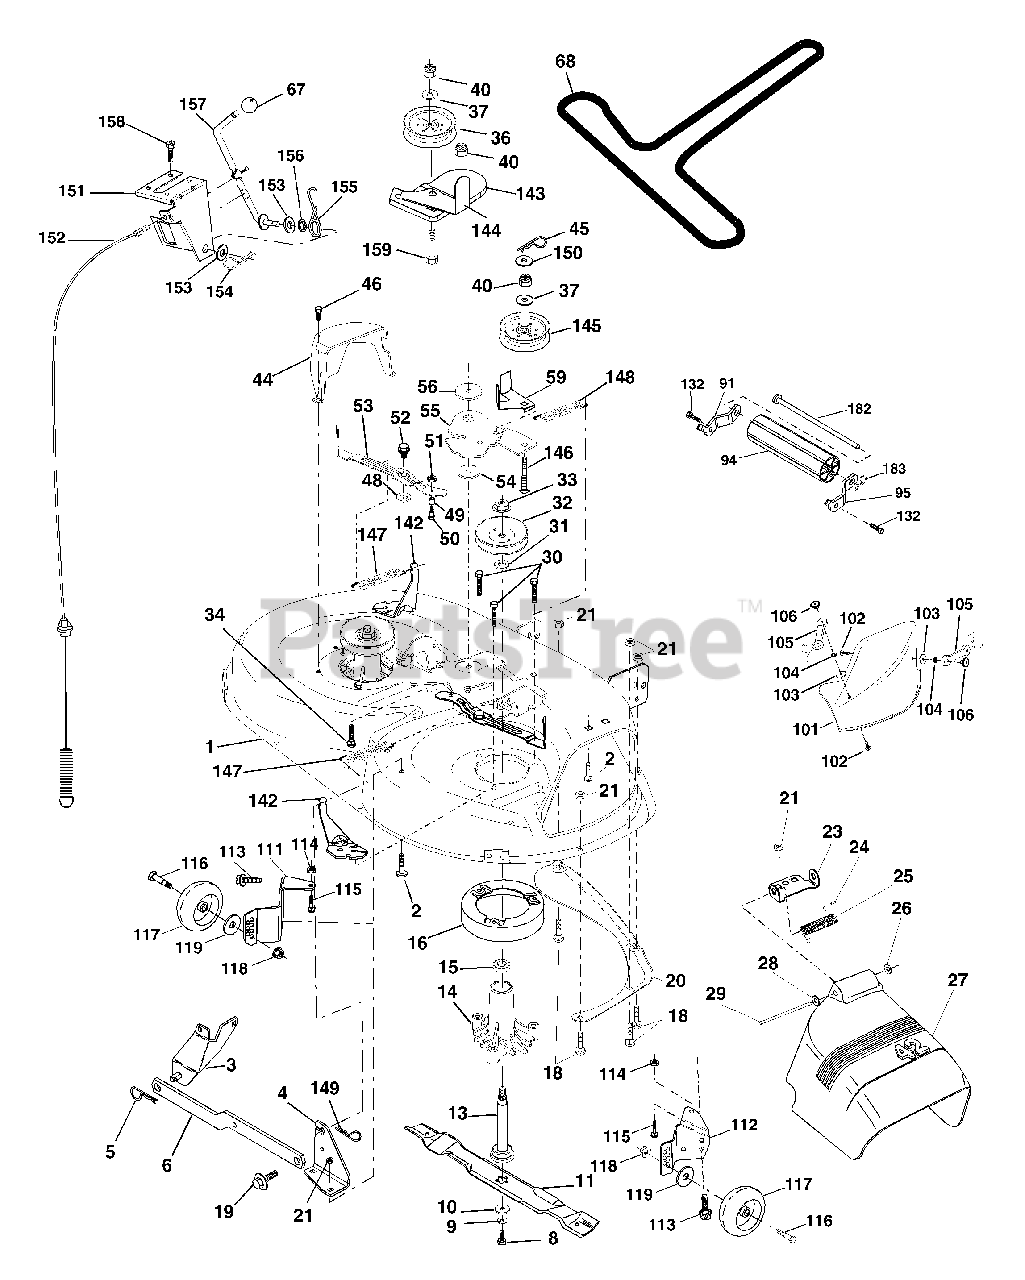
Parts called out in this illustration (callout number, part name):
1	Mower Deck Assembly, 42"
2	Bolt
3	Bracket Asm Fr. Sway Bar 3/42
4	Bracket Asm Deck 42" Sway Bar
5	Retainer Spring
6	Bar Sway Deck
8	Bolt 3/8-24 x 25 Gr. 8 patched
9	Washer, Lock
10	Washer, Hardened
11	Blade, Mulching 42" Std
11	Blade Mower 42" Hi-Lift Std
13	Shaft Assembly, Mandrel, Vented
14	Housing, Mandrel, Vented
15	Bearing, Ball, Mandrel
16	Stripper, Mower Deck
18	Bolt, Carriage 5/16-18 x 5/8
19	Bolt, Shoulder
20	Baffle, Vortex
21	Nut
23	Bracket, Deflector Mower 42"
24	Cap, Sleeve 80 x 112 Blk Mower
25	Spring, Torsion, Deflector 2 52
26	Nut, Push Phos & Oil
27	Shield, Deflector 42" Blk
28	Washer 11/32 x 5/8 x 16 Ga.
29	Rod, Hinge 42" 6 75 W/G
30	Screw Thdrol
31	Washer, Spacer Mower Vented
32	Pulley, Mandrel
33	Nut, Toplock 9/16
34	Bolt
36	Pulley, Idler, Flat
37	Washer 13/32 x 13/16 x 16 Ga.
40	Nut
44	Guard, Mandrel, LH
45	Retainer
46	Screw, Thdrol 1/4-20 x 5/8 T
48	Washer, Hardened
49	Roller Assembly, Cam Follower
50	Bolt, Shoulder #10-24 Grade 5
51	Locknut
52	Bolt, Shoulder 5/16-18 Unc
53	Arm Assembly, Pad, Brake
54	Washer, Hardened
55	Arm, Idler
56	Spacer, Retainer
59	Guard TUV Idler
67	Knob Round
68	V-Belt, 42" Mower
91	Bracket Roller Nose Lh
94	Roller Nose 38 & 42
95	Bracket Roller Nose Rh
101	Mulcher Cover
102	Screw Pan Hd Phillips 10-24 x 5/8
103	Washer, Flat
104	Washer, Lock
105	Latch Assembly
106	Nut, Weld
111	Bracket, Ga., Wheel LH
112	Bracket, Ga., Wheel RH
113	Screw 3/8-16 x .625
114	Nut, Keps 5/16 - 18 Unc
115	Bolt, Carriage 5/16-18 x 5/8
116	Bolt, Shoulder
117	Wheel, Ga.
118	Nut Centerlock 3/8-16
119	Washer 3/8 x 7/8 x 14 Ga.
121	Bracket, Extruded
132	Screw 3/8-16 x .75
142	Arm Spring Brake Mower
143	Bracket Arm Idler 42"
144	Keeper Belt 42" Clutch Cable
145	Pulley Idler Flat
146	Bolt Carriage Idler
147	Spring Extension
148	Spring Return Idler
149	Retainer Spring Yellow
150	Washer 9/32 x 3/4 x 16 Ga.
151	Bracket Clutch Cable
152	Clutch Cable 42"
153	Washer Flat 3/8" Type B
154	Spring Retainer
155	Spring Retention LVR CLTCH CAB
156	Spacer Clutch Cable
157	Rod Clutch Cable 3/8"
158	Screw Hex Thd Cut 1/4-20 x 1/2
159	Bolt Rdhd Sqn 3/8-16 Unc x 1-3/4
182	Rod Roller Nose
183	Retainer Spring
